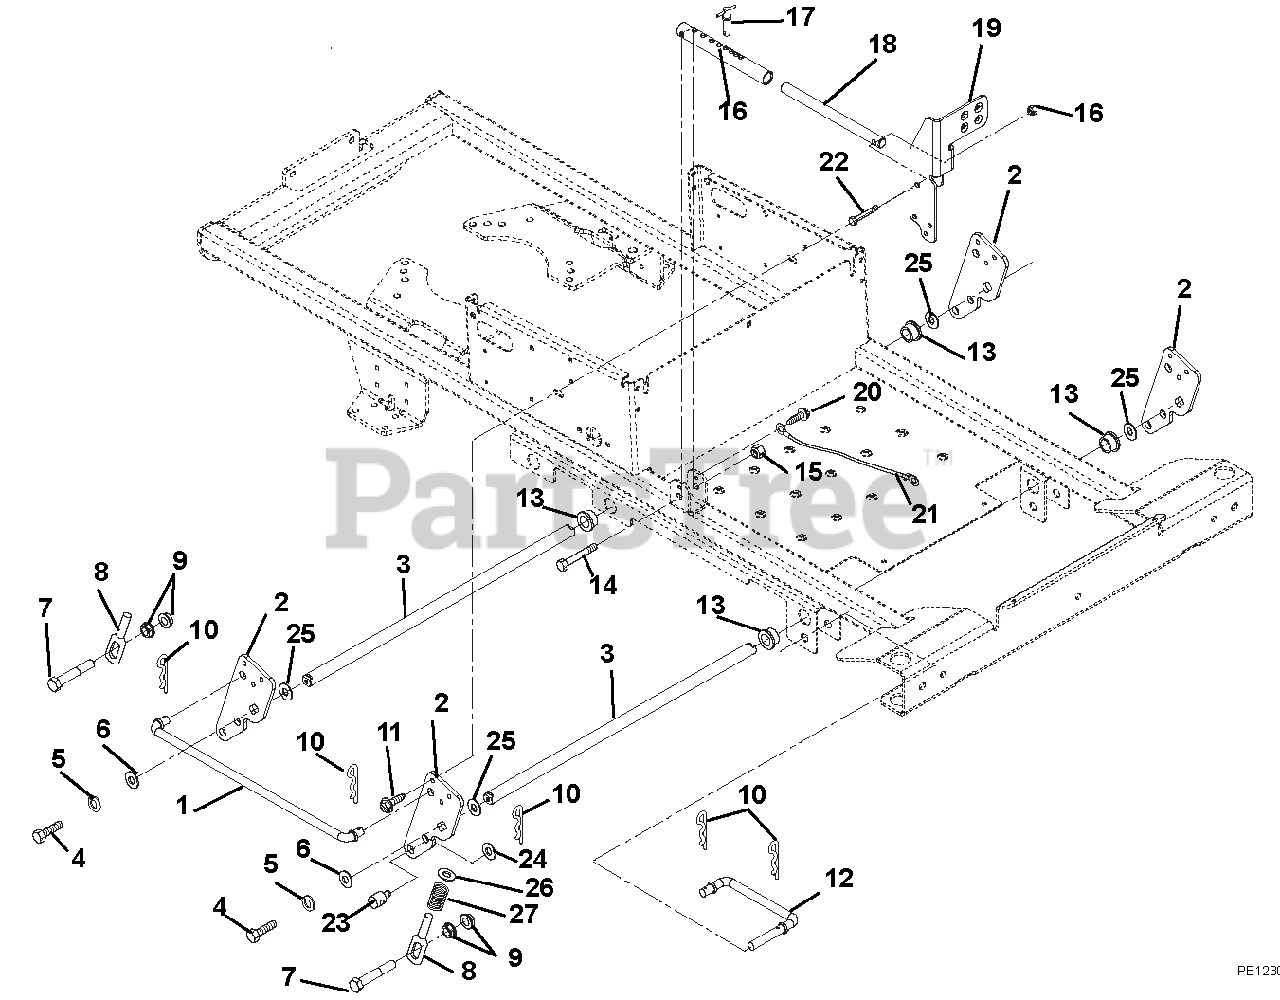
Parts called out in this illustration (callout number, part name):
1	ROD,LIFT
2	LIFT ARM
3	SHAFT,LIFT
4	@BLT-HEX .31-18X1.00 GR5 YWZC
5	WSHR-FL-STL .328X.87X.179 YWZC
6	WSHR-FL-STL .344X1.125X.135
7	@BLT-HEX .50-13X3.00 GR5 YWZC
8	DECK LINK
9	NUT-SPNLK-FLG .50-13 YWZC
10	PIN, HAIR, EXT - #16 YWZC
11	@SCR-TAP .31-18X.50 HWH TR YWZ
12	LINK,DRAG
13	BSHG-FLG .750X1.000X.625X1.250
14	@BLT-HEX .38-16X2.00 GR5 YWZC
15	@NUT-LK-NYL-FLG .38-16 YWZC
16	TUBE,LIFT STOP
17	PIN, SPRING BALL .375OD X 1.50
18	ROD,LIFT
19	PEDAL,FOOT LIFT
20	@SCR-TAP .25-20X.50 HWH TR YWZ
21	CBL,HOOD
22	@BLT-HEX .38-16X2.50 GR5 YWZC
23	TRUNNION-.50
24	WSHR-FL-STL.511X1.441X.125 YWZ
25	WSHR-FL-STL.755X1.375X.062YWZC
26	WSHR-FL-STL .515X1.625X.250 YZ
27	SG-COMP .105X1.35X2.00
